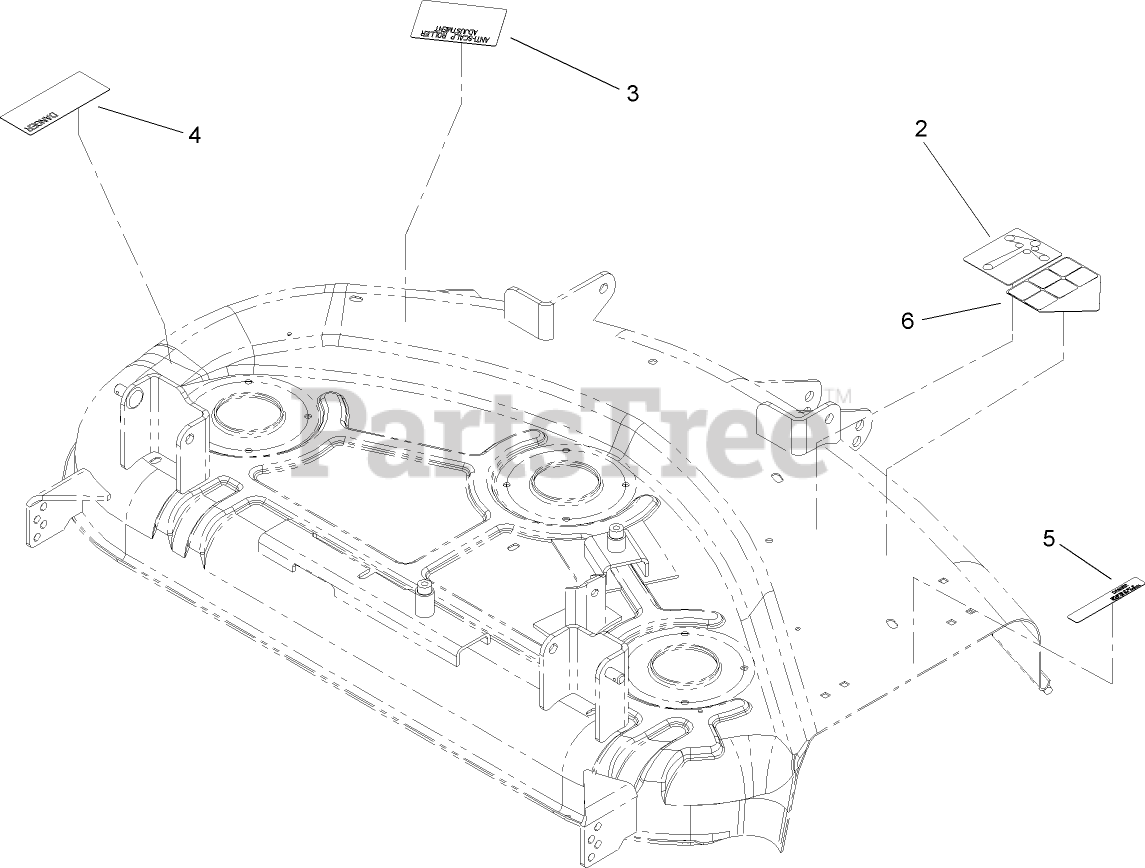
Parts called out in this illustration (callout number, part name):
2	DECAL-ROUTING, BELT
3	DECAL-ANTI SCALP
4	DECAL-DANGER
5	DECAL-DANGER
6	DECAL-DANGER
